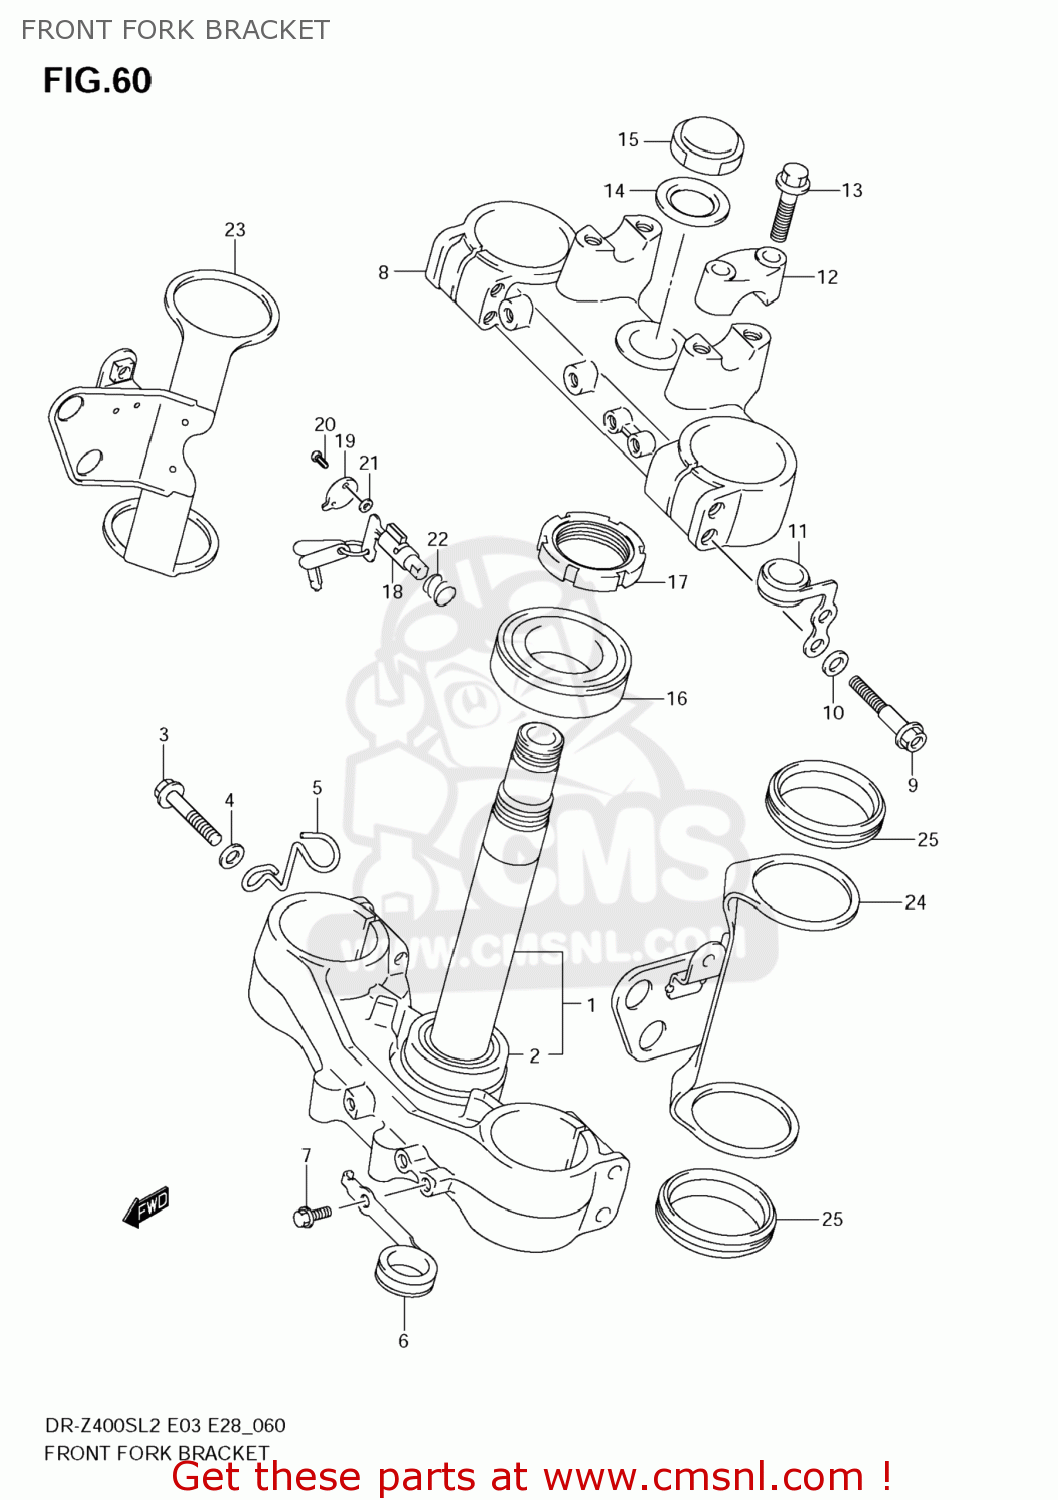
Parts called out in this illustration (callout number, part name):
1	BRACKET,FR FORK UNDER
2	BEARING(30X52X16)
3	BOLT
4	WASHER
5	GUIDE,SPEEDOMETER CABLE
6	GUIDE,CABLE
7	BOLT,PROTECTOR(6X10)
8	BRACKET,FR FORK UPR
9	BOLT
10	WASHER
11	GUIDE,CABLE
12	HOLDER,HANDLEBAR UPR
13	BOLT,HANDLE HOLDER(8X35)
14	WASHER,STEM HEAD
15	NUT
16	BEARING(30X52X16)
17	NUT,STEERING
18	LOCK ASSY,STEERING
19	CAP,STEERING LOCK
20	PIN,STEERING LOCK
21	WASHER,STEERING LOCK
22	SPRING,STEERING LOCK
23	BRACKET,HEADLAMP HOUSING,R
24	BRACKET,HEADLAMP HOUSING,L
25	DAMPER,HEADLAMP HSG BRACKET
